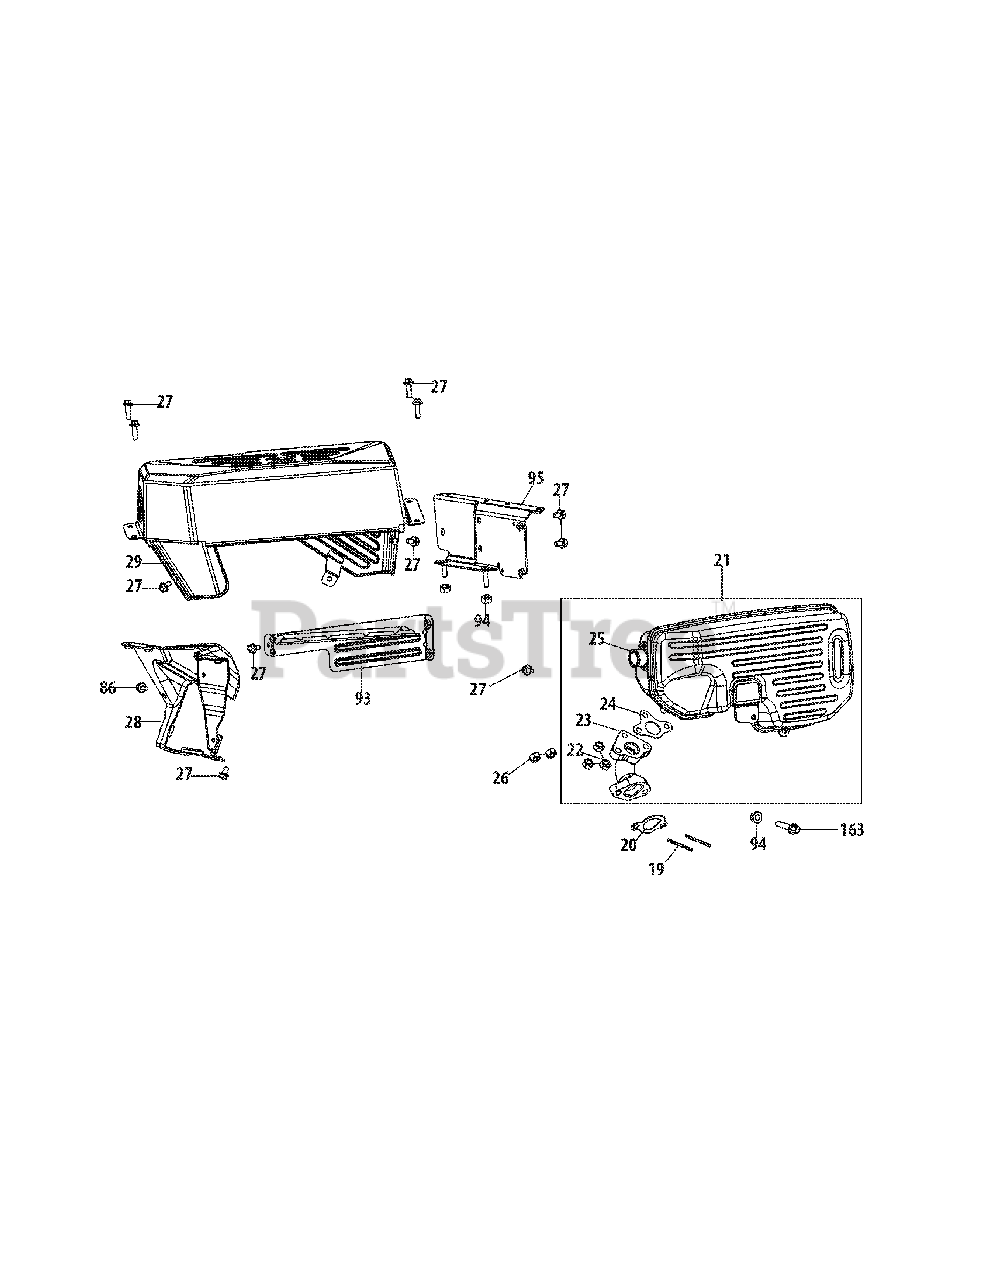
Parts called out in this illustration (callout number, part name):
19	STUD M8×36
20	MUFFLER GASKET
21	MUFFLER
22	NUT M8
23	EXHAUST PIPE
24	GASKET, MUFFLER
25	MUFFLER BODY
26	NUT M8
27	BOLT M6×12
28	FRONT BRACKET, FUEL TANK
29	MUFFLER GUARD
86	BOLT M6×16
93	FUEL TANK INSULATOR
94	FLANGE NUT M6
95	FUEL TANK BRACKET
163	BOLT M6×20
